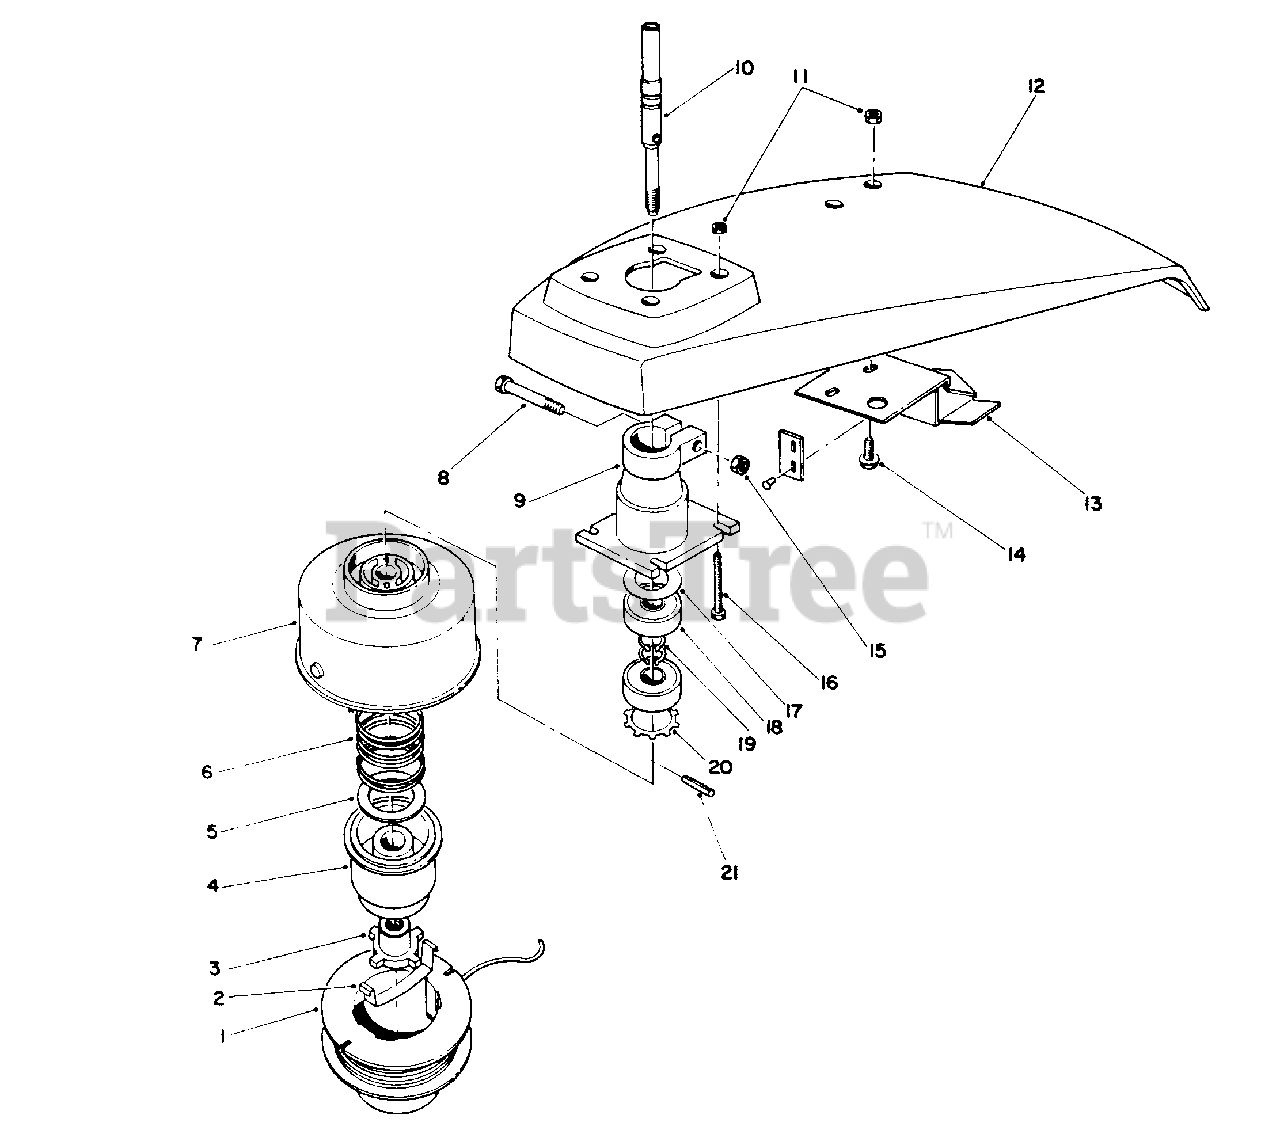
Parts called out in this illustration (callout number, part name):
1	Spool & Line Assembly
2	Saddle-Spool Cap
4	Core-Spool
6	Spring-Compression
7	Drum & Eyelet Assembly
8	Screw-Hex. Hd. Cap
9	Housing-Bearing (Incl. Ref. #10, 17-21)
10	Shaft-Power
11	Nut-Lock
13	Bracket & Knife Blade
14	Screw-Hex. Washer Hd
15	Nut-Lock
16	Screw-Hex. Washer Hd.
18	Bearing-Ball
19	Ring-Retaining
20	Spring-Grip
21	Pin-Coil
